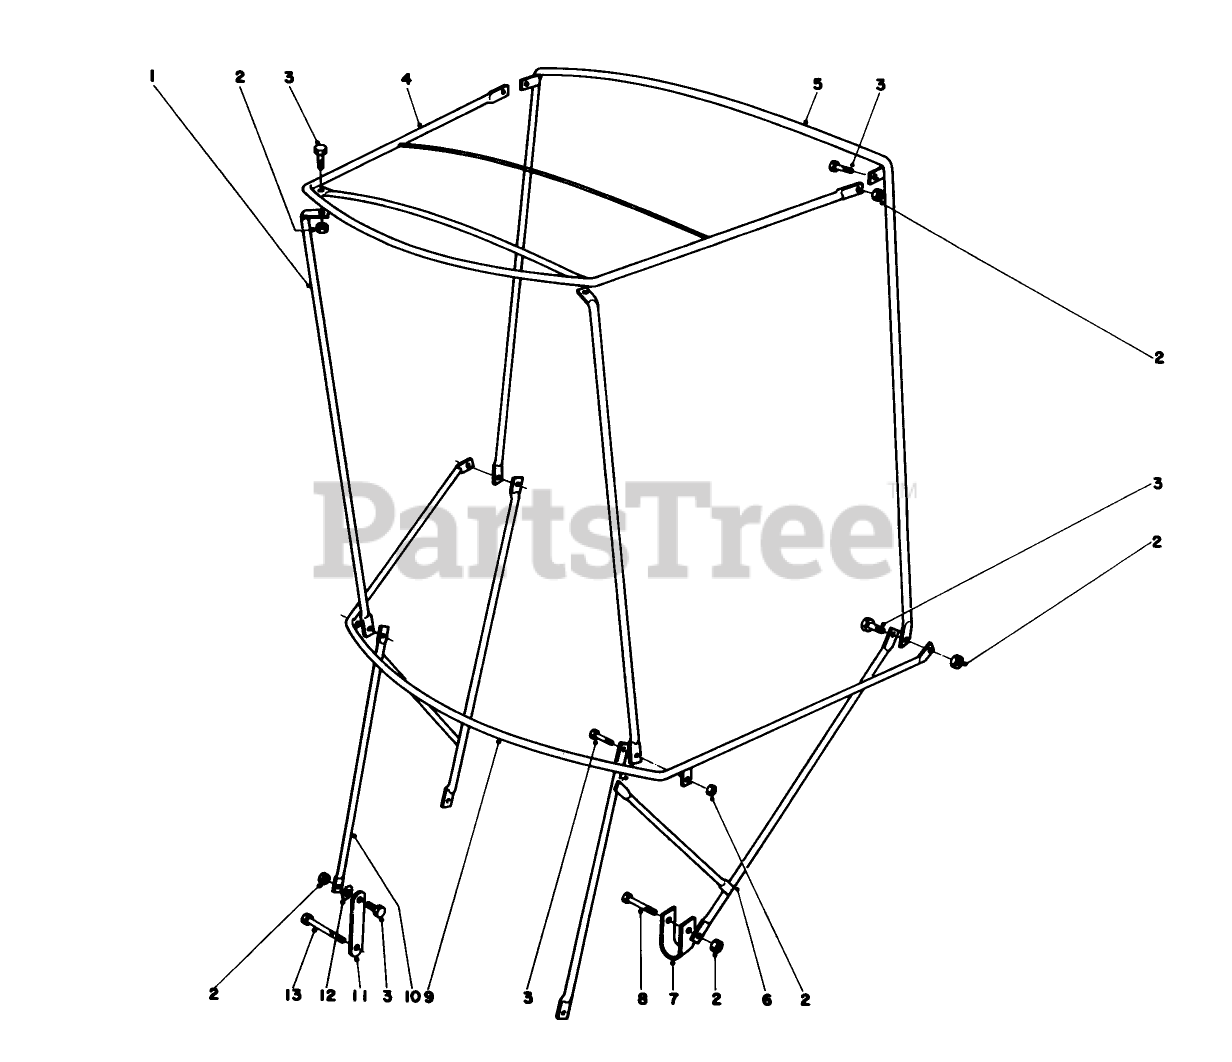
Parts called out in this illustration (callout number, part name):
3	Bolt
8	SCREW-HH
12	WASHER-LOCK/EXT
13	SCREW-HH
